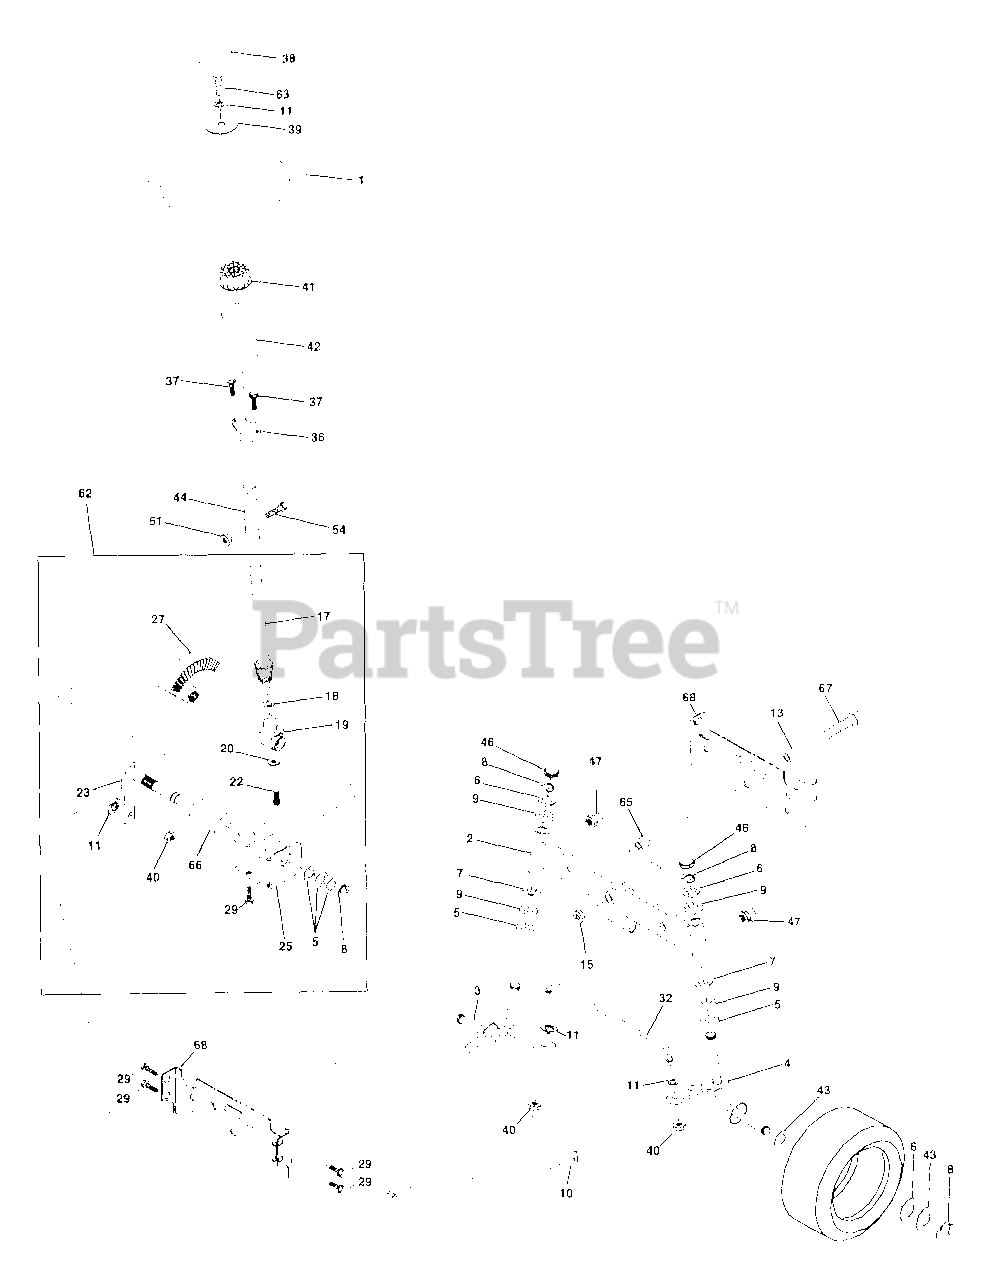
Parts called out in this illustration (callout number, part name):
1	Wheel Steering
2	Axle Front Casting Machined
3	Spindle Asm LH Cast 15"
4	Spindle Asm RH Cast 15"
5	Bearing Race Thrust Harden
6	Washer 25/32 X 1-5/8 X 16 Ga
7	Washer 27/32 X 1-1/4 X 16 Ga
8	Ring Klip #t5304-75
9	Bearing Col Strg Blk
10	Link Drag Extended Cast
11	Washer Lock Hvy Hlcl Spr 3/8
13	Bearing Axle STLT/GT
15	Nut Lock Flange 5/8-11 Unc
17	Shaft Asm Strg
18	Washer Thrust 515 x 750 x 033
19	Support Shaft
20	Washer Shim 1/4 X 5/8 X 062
22	Screw Hex Socket 1/4-20 x 5/8
23	Shaft Asm Pittman
25	Bracket Steering
27	Gear Sector
29	Screw Thdrol 3/8-16 x 3/4 Ty-tt
32	Rod Asm Tie Ball J Adj VGT
36	Bushing Strg
38	Insert Cap Strg Wh Au
39	Washer 13/32 X 2-3/8 X 8 Ga
40	Lock nut
41	Adaptor Wheel Strg
42	Boot Steering Shaft
43	Washer 25/32 X 1 1/4 X 16 Ga
44	Extension Steering Shaft LR/LT
46	Cap Spindle Fr Top Blk
47	Fitting Grease
51	Nut Lock Hex w/Ins 5/16-18
53	Nut Crownlock 3/8-16 UNC
54	Bolt Fin Hex 5/16-18 Unc x 1-1/4
62	Kit, Steering Assembly Svc
63	Bolt Fin Hex 3/8-16 unc x 1 Gr. 5
65	Spacer Axle
66	Bearing Arm Pittman
67	Bolt, Fin Hex 5/8-11 UNC x 2-3/4
68	Axle, Brace
69	Spacer Brace Axle
70	Bolt Fin Hex 3/8-16 UNC x 2-1/4
